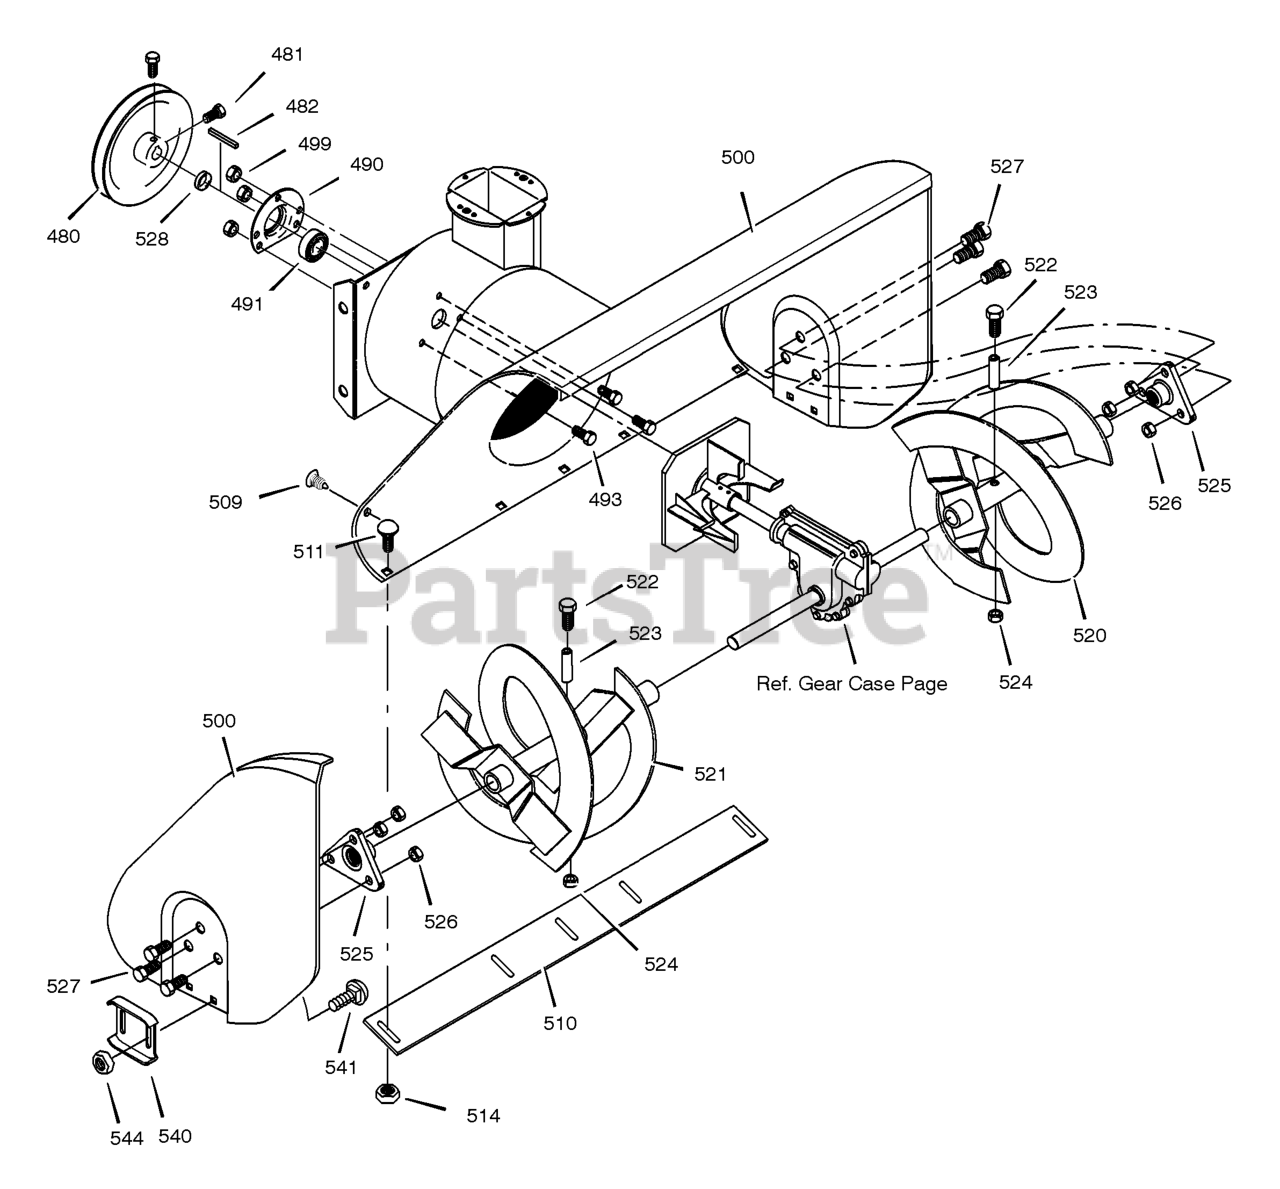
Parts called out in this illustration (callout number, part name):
480	PULLEY, 4L 6.12X .67
481	SCREW, 5/16-18 x 0.63
482	KEY, SQUARE 3/16 X 3/4
485	SPACER, FRICTION PULLEY
490	RETAINER, BALL BRNG
491	BEARING, BALL
493	BOLT, HEX 5/16-18X .50
499	NUT, 5/16-18 HEXWDFLLK
500	HOUSING, ASSY
502	FASTENER, RATCHET
510	BLADE, SCRAPER 24"
511	BOLT, 1/4-20X.75
514	NUT, 1/4-20
520	AUGER, ASSY, LH
521	AUGER, ASSY, RH
522	SCREW, 1/4-20X1.75
523	SPACER, SLEEVE
524	NUT, 1/4-20
525	BEARING,FLANGE
526	NUT, 5/16-18
527	SCREW, 5/16-18 x 0.75
540	SKID, HEIGHT ADJUST
541	BOLT, 5/16-18 X .75
544	NUT, 5/16-18
